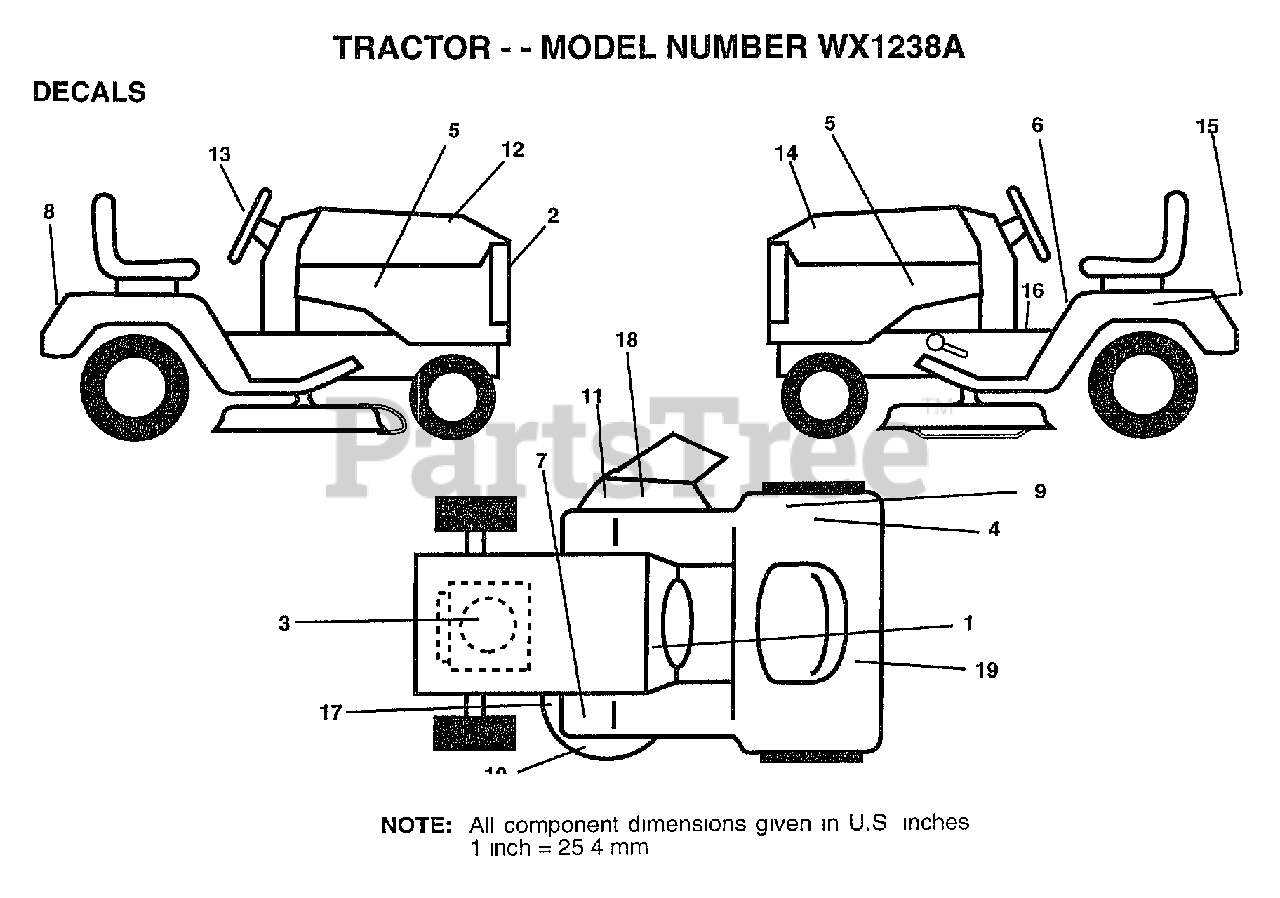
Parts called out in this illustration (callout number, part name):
2	DECAL.GRILL
3	DECAL.ENG.271967
4	DECAL.EURO.ST.CE.
5	DECAL.PNL.SIDE.12
6	DECAL.READ.O.MANU
8	DECAL.FENDER
10	DECAL.MOWER
12	DECAL.HD.STRIP.RH
13	DECAL.WHL.STRG.
14	DECAL.HD.STRIP.LH
16	DECAL BRAK PARK
17	DECAL
18	DECAL.DANGER.CUTF
19	DECAL.BATRY.3-3908
